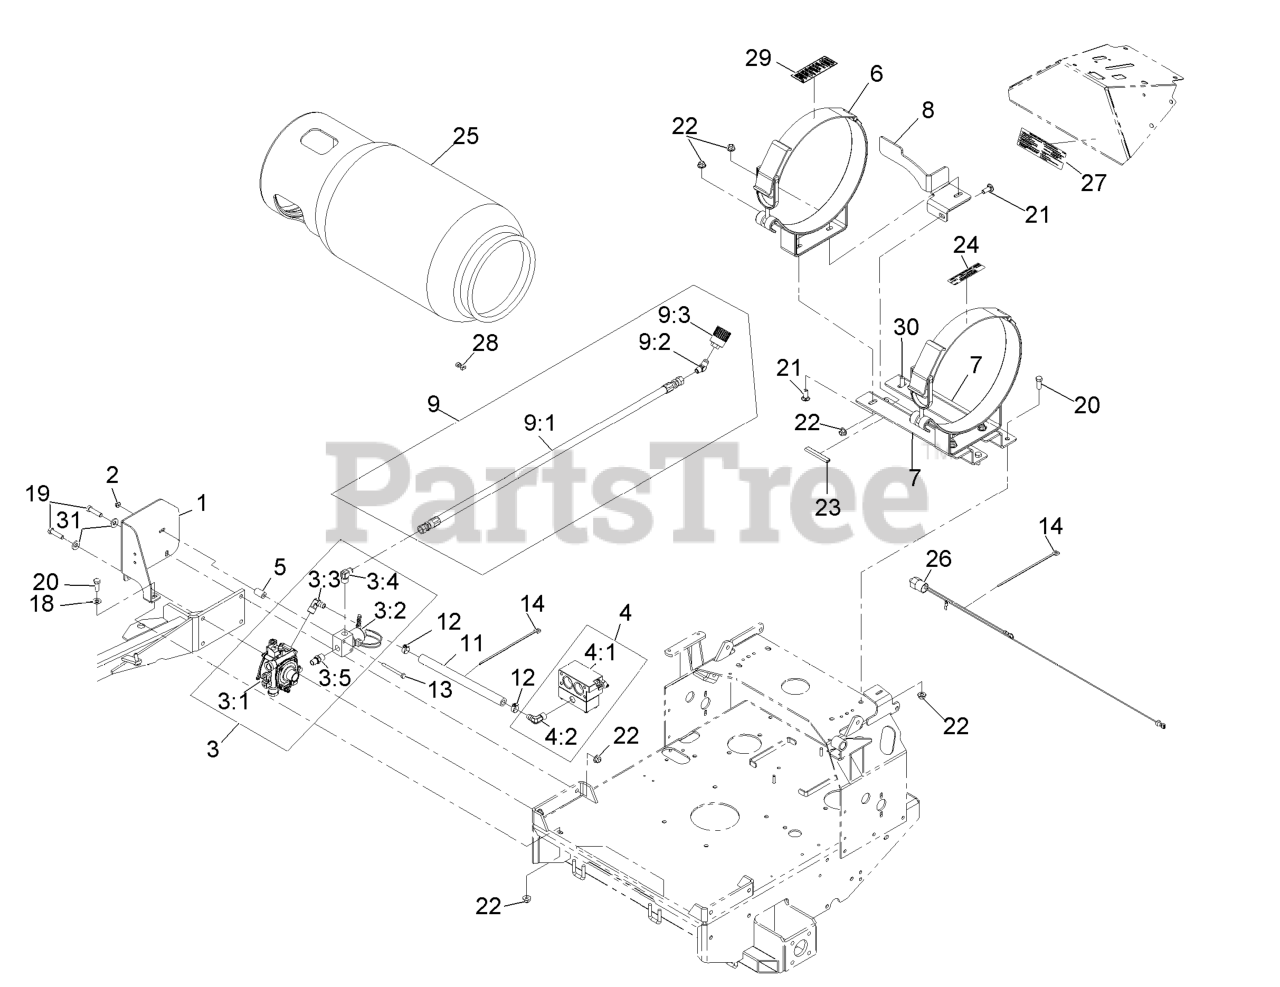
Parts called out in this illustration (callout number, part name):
1	REGULATOR MOUNT-TT
3	Asm, Reg And Shutoff
3:1	Regulator-Lp, T60
3:2	LPG SOLENOID VALVE ASM
3:3	ELBOW-90 DEG
3:4	ELBOW 90,3/8NPT X 3/8SAE
3:5	COUPLING-PIPE, MALE
4	Asm, Mixer
4:1	MIXER,LP FX691V
4:2	ELBOW-90 DEG
6	BRACKETS, LPG TANK - HORI
7	RISER, LPG TANK
8	BRACKET, LPG TANK INDEX
9	Asm, Lpg Fuel Hose
9:2	ELBOW-45 DEG
9:3	CONNECTOR-LPG TANK, LH TH
11	HOSE-LP
12	CLAMP-HOSE
13	SCREW-HH
14	TIE-PLASTIC
18	WASHER-FLAT
19	SCREW-HH
20	SCREW-HH
21	SCREW-CARR
22	NUT-HF, NI
23	STRIP-SEAL
24	DECAL,LPG TANK SPEC HORIZ
25	TANK,LPG 33LB
27	DECAL-TANK REPLACEMENT
28	RECEPTICAL -FEM, .250, IN
29	DECAL-LPG WARNING
30	BOLT-CARR
31	WASHER-BELLEVILLE
